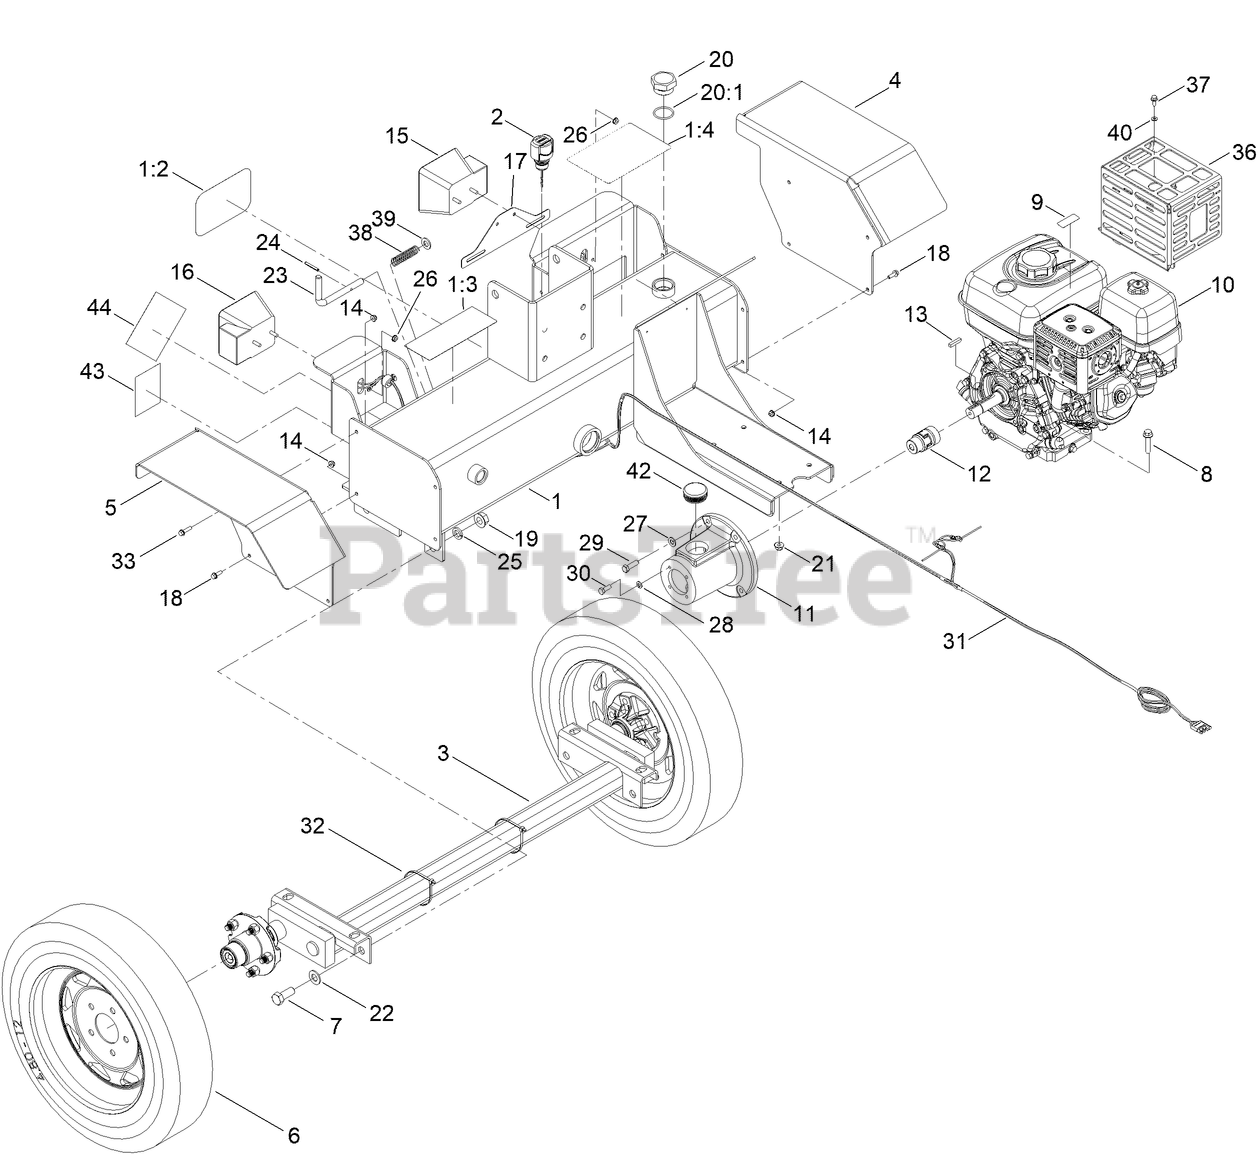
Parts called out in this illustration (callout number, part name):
1	HYD TANK ASM
1:2	DECAL
1:3	DECAL-WARNING
1:4	DECAL-SERVICE , 23618[HD]]
2	BREATHER
3	AXLE ASM
4	FENDER-LH
5	FENDER-RH
6	WHEEL AND TIRE ASM
7	SCREW-HH
8	SCREW-HHF
9	DECAL-WARNING, ETHANOL
10	ENGINE-HONDA, GX270
11	MOUNT-PUMP [BLACK]
12	COUPLER-FLEX
13	KEY-SQUARE
14	NUT-HF
15	LIGHT-TAIL, LH
16	LIGHT-TAIL, RH
17	HOLDER-PLATE, LICENSE
18	SCREW-HHF
19	NUT-FLANGE
20	PLUG-HH
20:1	O-RING
21	NUT-HF, NI
22	WASHER
23	PIN-LATCH
24	PIN-ROLL
25	WASHER-LOCK
26	NUT-KEPS
27	WASHER-FLAT
28	WASHER-LOCK
29	SCREW-HH
30	SCREW-HH
31	HARNESS-WIRE
32	TIE-CABLE
33	SCREW-HHF
36	GUARD-MUFFLER
37	SCREW-HHF
38	SPRING-COMPRESSION
39	WASHER-FLAT
40	WASHER-FLAT
42	PLUG-PLASTIC
43	DECAL- RHVSG3X4
44	DECAL-CPER0001
